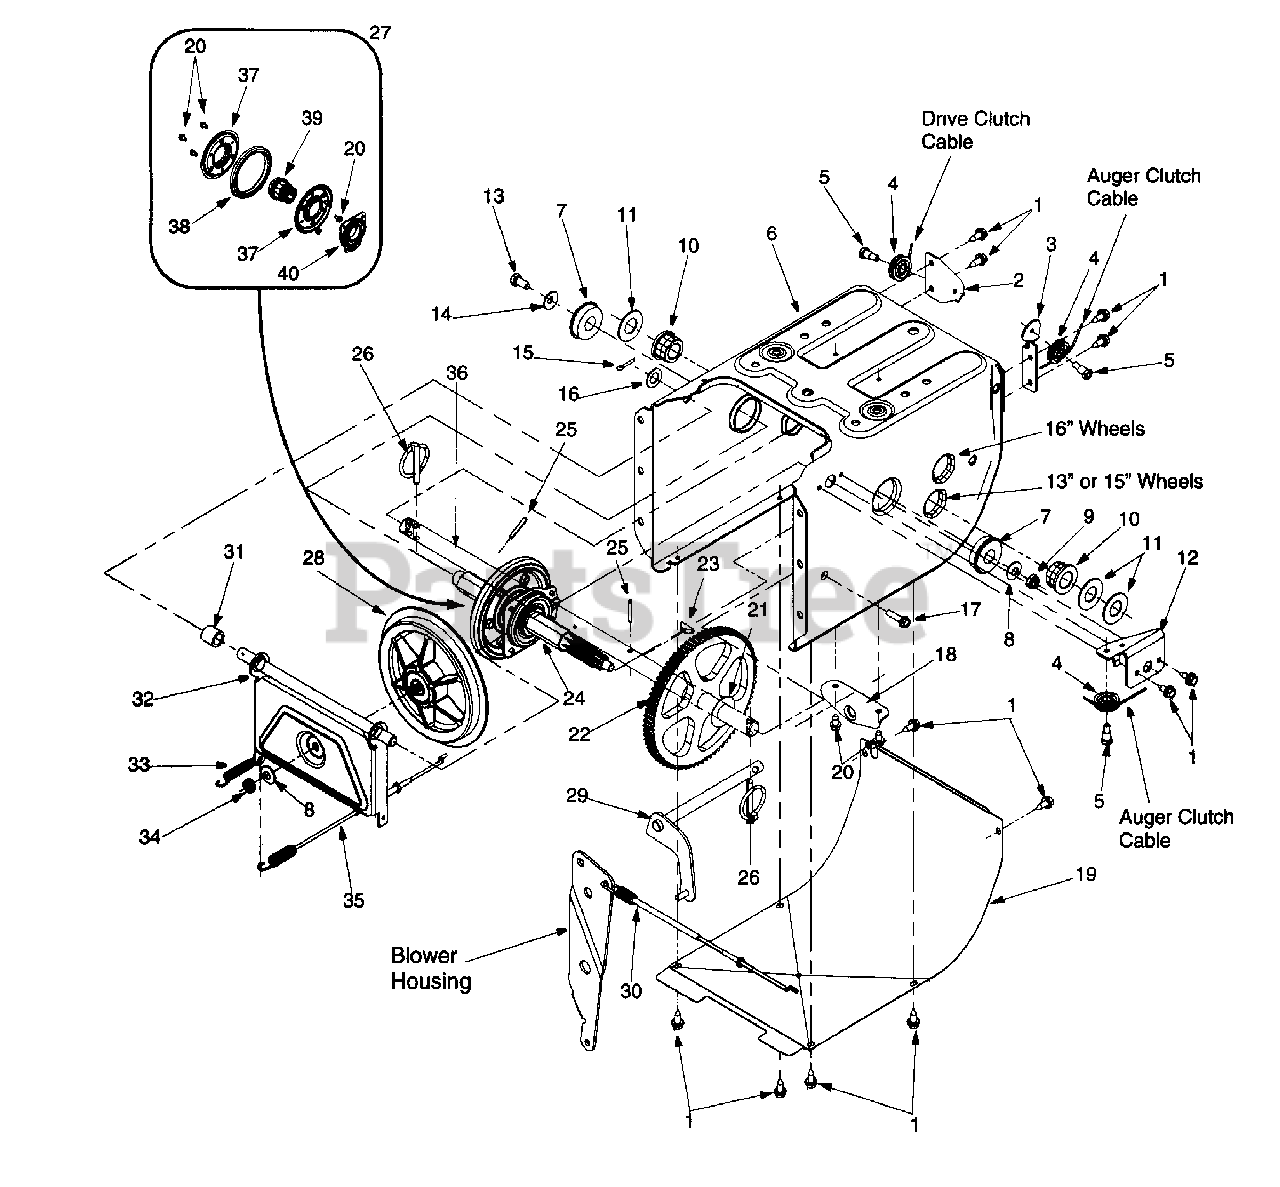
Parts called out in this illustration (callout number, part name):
1	Hex Screw
5	Hex Screw 1/4-28
8	Bell Washer
9	Lock Jam Nut
10	Hex Flange Bearing
11	Flat Washer
14	Bell Washer .340 ID x .872 OD
15	Cotter Pin
16	Flat Washer .536 ID x .930 OD
17	Hex Washer Screw 1/4-20
21	Flat Washer .760 ID x .50 OD
24	7-Tooth Shaft
25	Roll Pin
26	Klik Pin
27	Friction Wheel Assembly
28	Friction Disc Wheel
29	Wheel Shift Rod Assembly
30	Drive Cable
31	Spacer
34	Jam Nut 3/8-24
35	Drive Cable
36	Axle 16" Wheels
37	Friction Plate
38	Friction Wheel Rubber
39	Friction Wheel Hub
40	Friction Wheel Bearing
